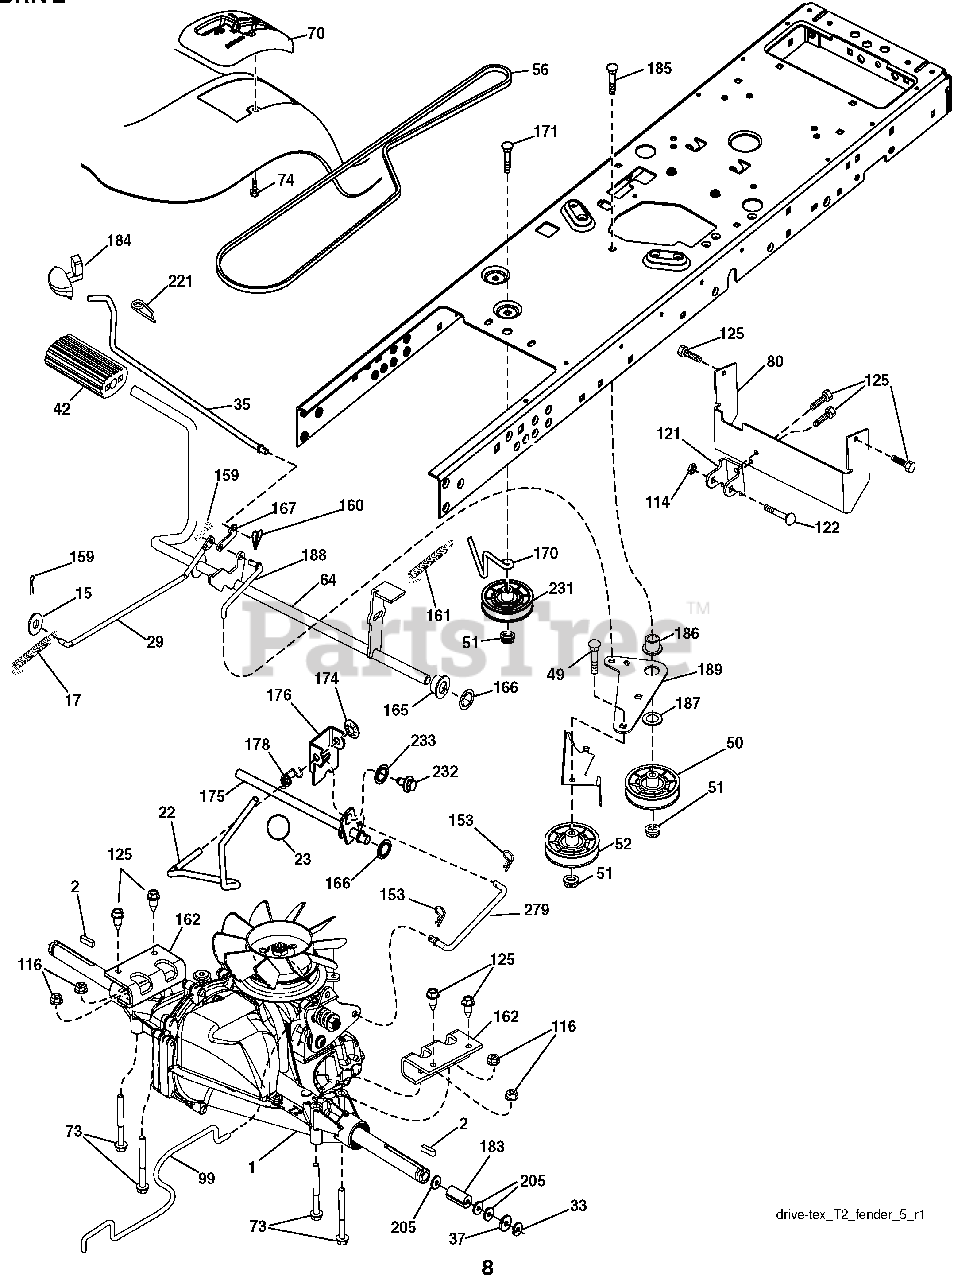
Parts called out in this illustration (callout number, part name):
1	Transaxle, Hydro Gear T2 (See Transaxle Breakdown)
2	Key Square
15	Washer 13/32 x 13/16 x 16 Ga.
17	Spring, Brake
22	Rod Shift
23	Knob
29	Rod, Brake
33	Ring E
35	Rod, Brake, Park
37	Washer 25/32 x 1-1/4 x 16 Ga.
42	Cover, Foot Pedal
49	Bolt
50	Pulley Idler Flat
51	Lock Nut 3/8-16
52	Idler V-Groove 910" Offset
56	V-Belt, Drive
64	Shaft Asm. Pedal Brake Control
70	Console
73	Bolt Hex 5/16-18 Gr. 5
74	Screw 1/4 x 1/2
80	Strap Torque
99	Rod Spring Bypass
114	Nut Lock 5/16-18 unc
116	Nut Lock Hex Flange 5/16-18
121	Bracket Strap Torque
122	Bolt 5/16-18 x 2.50
125	Screw 5/16-18 x 3/4
153	Retainer Spring 1"
159	Pin Cotter 1/8 x 3/4
160	Retainer Clip
161	Spring, Return, Clutch
162	Adapter Transaxle
165	Bushing
166	Nut Push .625
167	Latch Brake Parking
170	Keeper Belt Centerspan
171	Bolt
174	Nut Push
175	Shaft Asm Shift
176	Arm Clevis Rod Shift
178	Spring Shift
183	Spacer Axle
184	Handle Parking Brake
185	Bolt
186	Spacer Retainer
187	Washer
188	Link Clutch Ground Drive
189	Bellcrank Ground Drive
190	Keeper Bellcrank Ground Drive
205	Washer 25/32 x 1-5/8 x 16 Ga.
221	Retainer Spring Clip Handle
231	Idler V-Groove 1.688" Offset
232	Bolt 7/16-14 x 1 Gr 5
233	Washer Serrated
279	Link Shift
